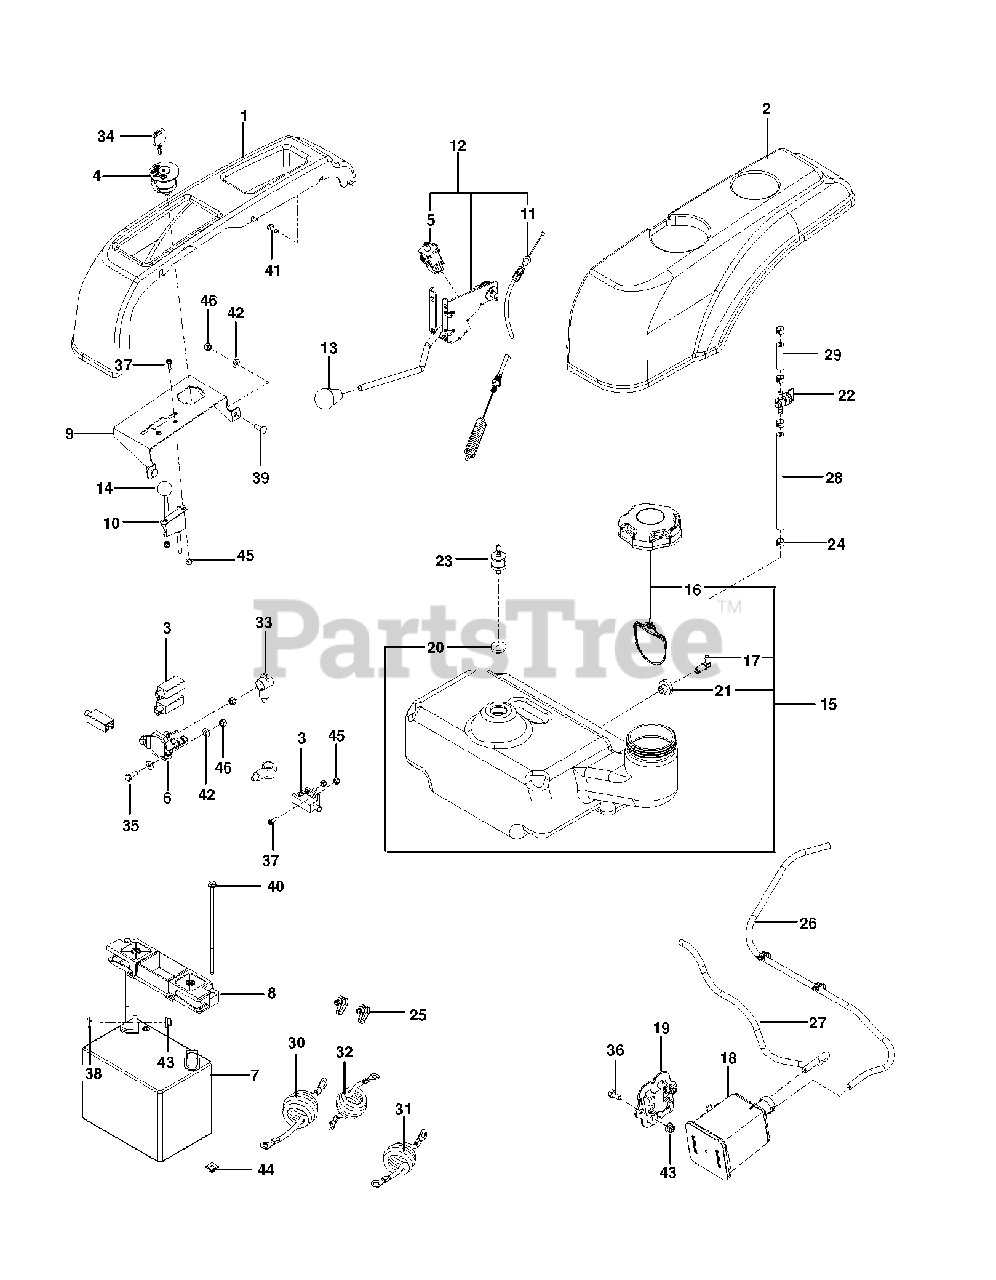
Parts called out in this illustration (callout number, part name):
1	FENDER, RZ 30/38 RT
2	FENDER, RZ 30/38 LT
3	SWITCH INTERLOCKT
4	RP IGNITION SWITCH
5	SWITCH INTERLOOK PUSH-IN
7	BATTERY, 12 V 330 AMP
8	BATTERY HOLD DOWN
9	MOUNT, CONTROLS, BLK
10	CABLE, THROTTLE
11	CABLE-CLUTCH ENGAGE
12	CLUTCH.ENGAGE.ASSEM.W/CABLE
13	KNOB - SHIFT
14	KNOB.ROUND.BALL.BLACK
15	FUEL TANK ASM SMALL
16	CAP, FUEL
17	STEM, FUEL TANK
18	CANNISTER, CARBON
19	BRACKET, CANISTER
20	GROMMET, CHECK VALVE
21	RUBBER GROMMET
22	FUEL VALVE
23	VALVE.FUEL.CHECK
24	HOSE CLAMP
25	TIE WRAP, 8-3/8", W/CLIP
26	FUEL LINE 33"
27	HOSE, FUEL, 3/16" X 20"
28	HOSE 1/4 X 8
29	HOSE 1/4 X 2"
30	POST.CABLE LONG
31	CABLE POSITIVE, LONG
32	BATTERY CABLE, NEGATIVE
33	TERMINAL COVER-SM
34	KEY
35	HCS 1/4C X 3/4 HCS
36	HCS 5/16-18 X 5/8 GR 5 ZD
37	SCREW #10-24 X 5/8
38	BOLT 5/16C X 3/4" CARRIAGE
39	RHSNB 1/4C X 3/4
40	Bolt, 1/4-20 X 7.5
41	SCREW 1/4 X 5/8
42	WASHER 1/4 SAE
43	5/16-18 NYLOC FLANGE NUT
44	PUSH NUT-NYLON
45	NUT 10-24 NYLOC
46	RP_NUT 1/4-20 NYLOC
